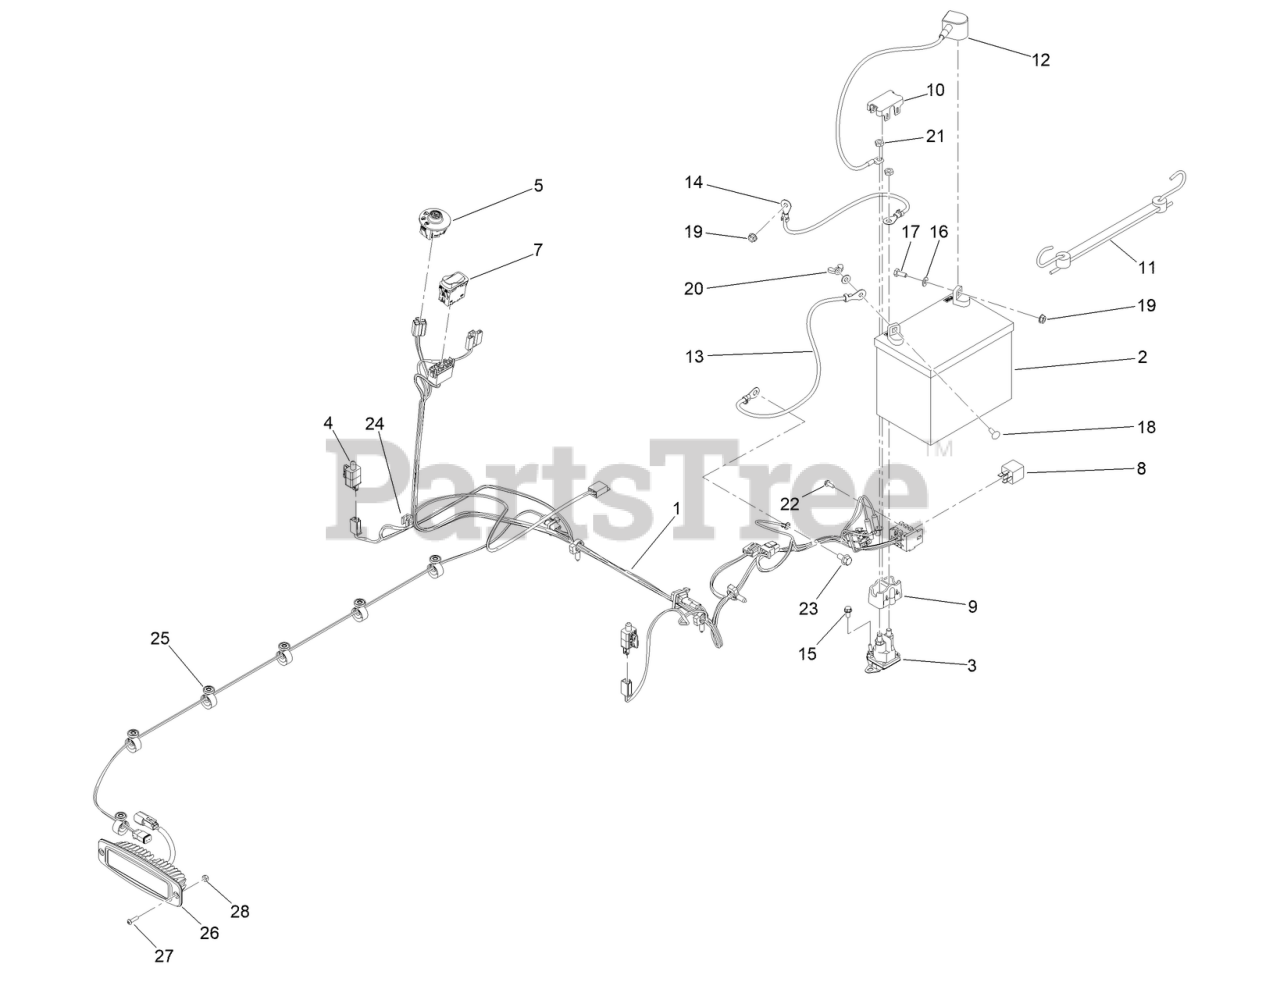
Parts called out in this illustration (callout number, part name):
1	HARNESS-WIRE, MAIN
3	SOLENOID
4	SWITCH
5	SWITCH-IGNITION
7	SWITCH-ROCKER, ON-NONE-ON
9	COVER-SOLENOID
10	CAP-SOLENOID
11	HOLDDOWN-BATTERY
12	CABLE-BATTERY,RED
13	CABLE-BATTERY, BLACK
14	CABLE-BATTERY, POSITIVE
15	SCREW-HWH
16	WASHER-FLAT
17	SCREW-HH
18	BOLT-CARR
19	NUT-HF
20	NUT-WING
21	NUT-JAM
22	SCREW-TAPTITE
23	SCREW-HHF
24	CLIP-EDGE W/TIE, PERPENDICULAR
25	HARNESS-WIRE. LED LIGHTS
26	MOUNT-FLUSH, LIGHT
27	SCREW-HSBH
28	NUT-LOCK, NI
